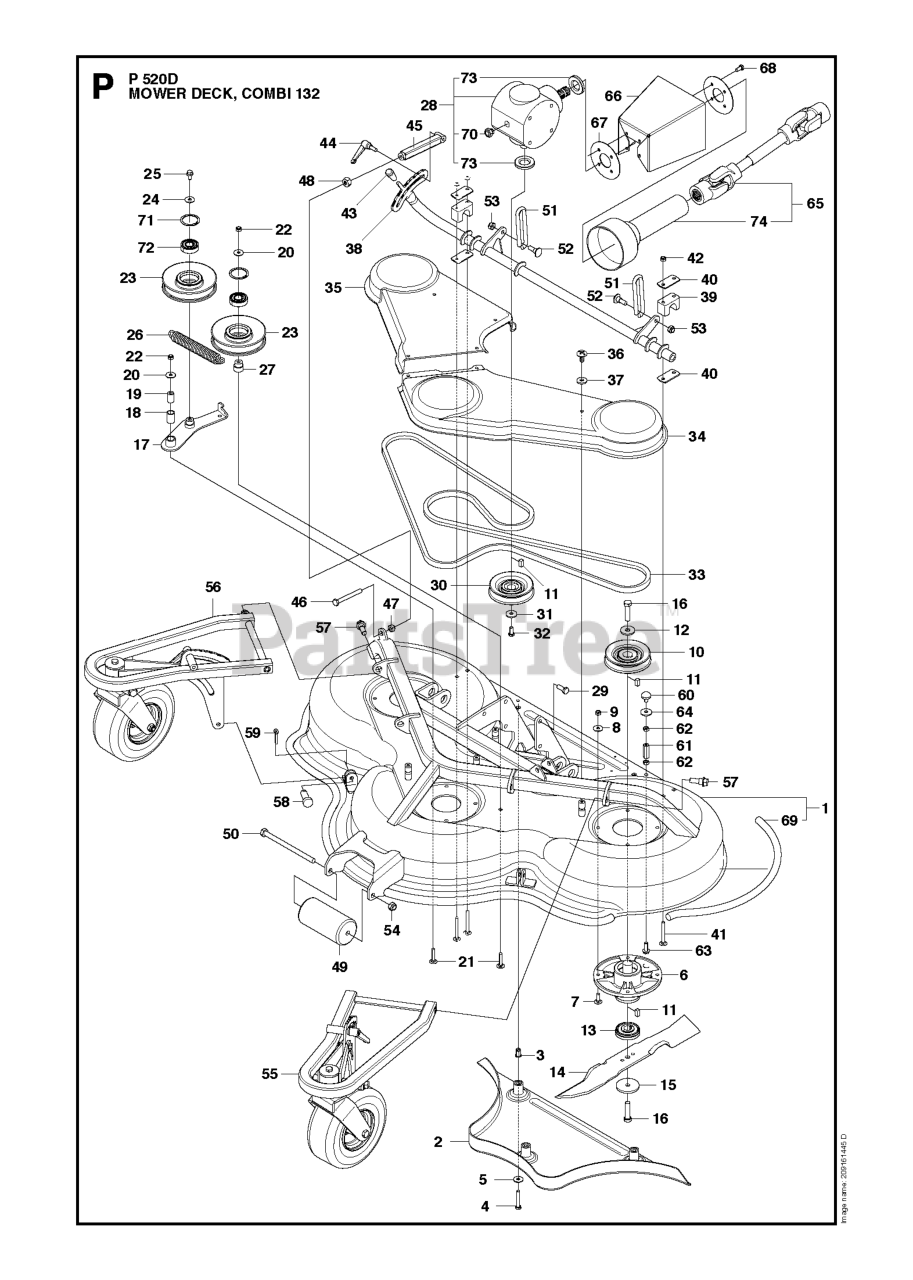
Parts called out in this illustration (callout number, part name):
1	CUTTING DECK ASSY C132
2	PLUG ASSY
3	BLIND RIVET NUT
4	BOLT
5	WASHER BRB 8.4X17
7	BOLT
8	WASHER BRB 8.4X17
9	LOCKNUT M8
11	KEY
14	BLADE REAR DISCHARGE/MULCH C13
15	WASHER
16	Screw
17	BELT TENSIONER CUTTING DECK
18	BEARING
19	BUSHING
20	SPACER
21	Screw Mvbf 8 X 40
22	LOCKNUT M8
24	SPACER
25	BOLT FLANGE - M8X16
26	DRAW SPRING L=122
27	BUSHING
28	BEVEL GEAR
29	Screw M10x25
30	PULLEY SPB DP106
32	SCREW
35	BELT COVER C132 R
36	SCREW
37	WASHER
38	CROSS BAR
40	PLATE
42	LOCKNUT M8
44	TURNING KNOB M 8
45	PARALLEL ROD C 132
46	SCREW
47	NUT
48	NUT
49	ROLLER
51	LINK
52	SCREW LINK
53	NUT
54	Nut
55	WHEEL SUSPENSION LEFT
56	WHEEL SUSPENSION RIGHT
57	BOLT
59	Split Pin
60	ANTIVIBRATION ELEMENT
62	NUT
63	BOLT
64	SPACER
68	BOLT
71	CIRCLIP SGH 47
72	BALL-BEARING 6204-2RS
